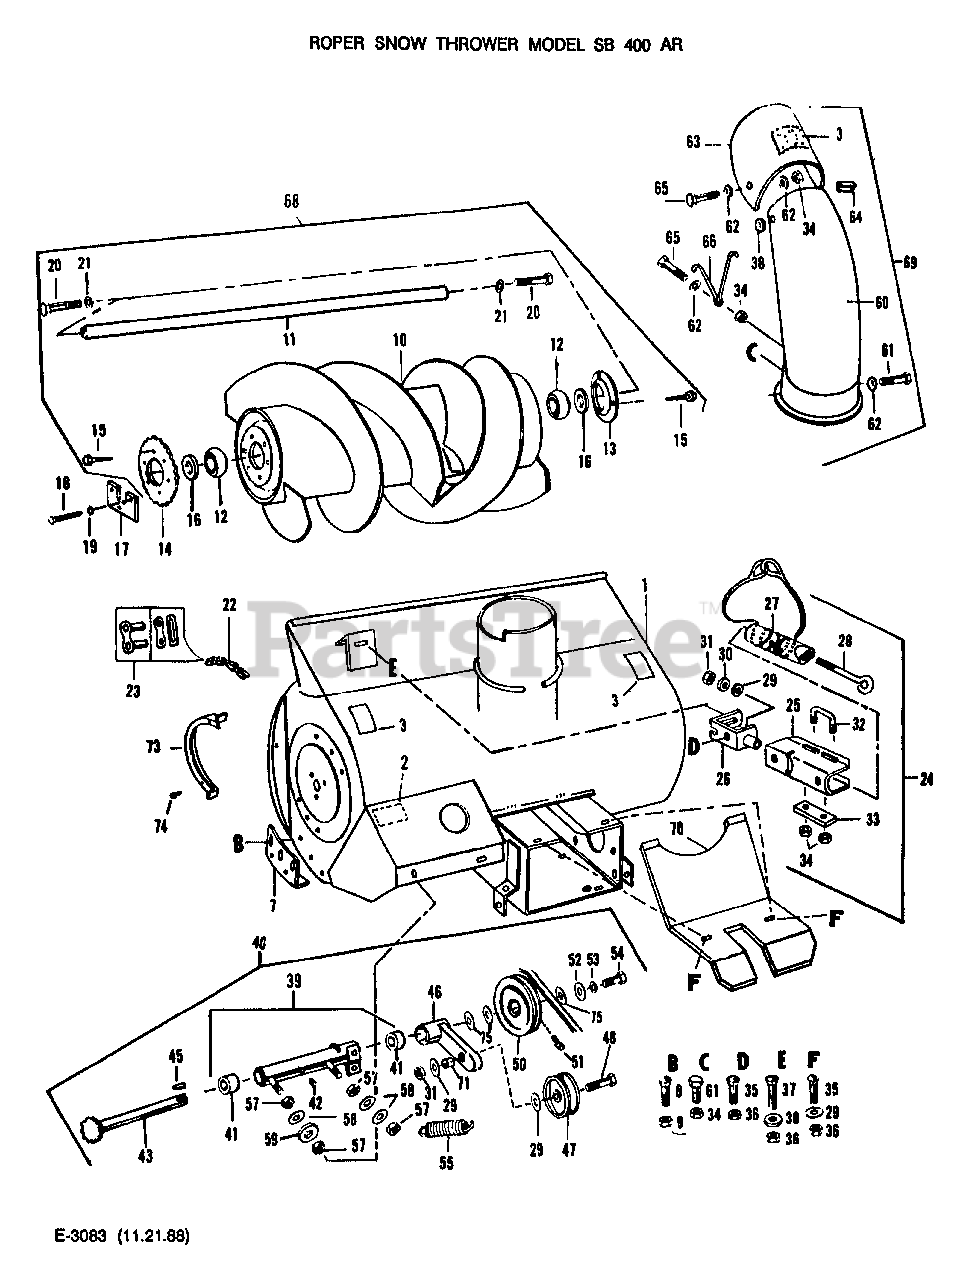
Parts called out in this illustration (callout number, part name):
1	HEADER & DECAL ASSY
9	NUT & WASHER ASSY
10	AUGER ASSY
11	AUGER SHAFT
12	AUGER SHAFT BEARING
13	BEARING FLANGE
14	AUGER SPROCKET
16	ASSY, GEAR
17	AUGER MOUNTING PLATE
22	AUGER DRIVE TRAIN
23	CHAIN REPAIR KIT
24	STACK DRIVE BRKT ASSY
25	STACK DRIVE SHROUD
26	BRACKET & TUBE ASSY
27	CABLE, TUBE & SLEEVE ASSY
30	SPRING WASHER
33	FRICTION STRAP
36	NUT & WASHER ASSY
39	JSHAFT HSG & BRG ASSY
40	JSHAFT HOUSING ASSY
42	GREASE FITTING
43	JSHAFT & SPROCKET ASSY
46	IDLER ARM ASSY
47	IDLER PULLEY ASSY
50	PULLEY & HUB ASSY
60	DEFLECTOR & ELBOW ASSY
62	CABLE WASHER
63	DECAL & DEFLECTOR ASSY
64	DEFLECTOR MOLDING
66	LIFT SPRING HOOK
68	AUGER ASSY
69	DEFLECTOR & ELBOW ASSY
70	DRIVE PULLEY GUARD
73	GUARD CHAIN
